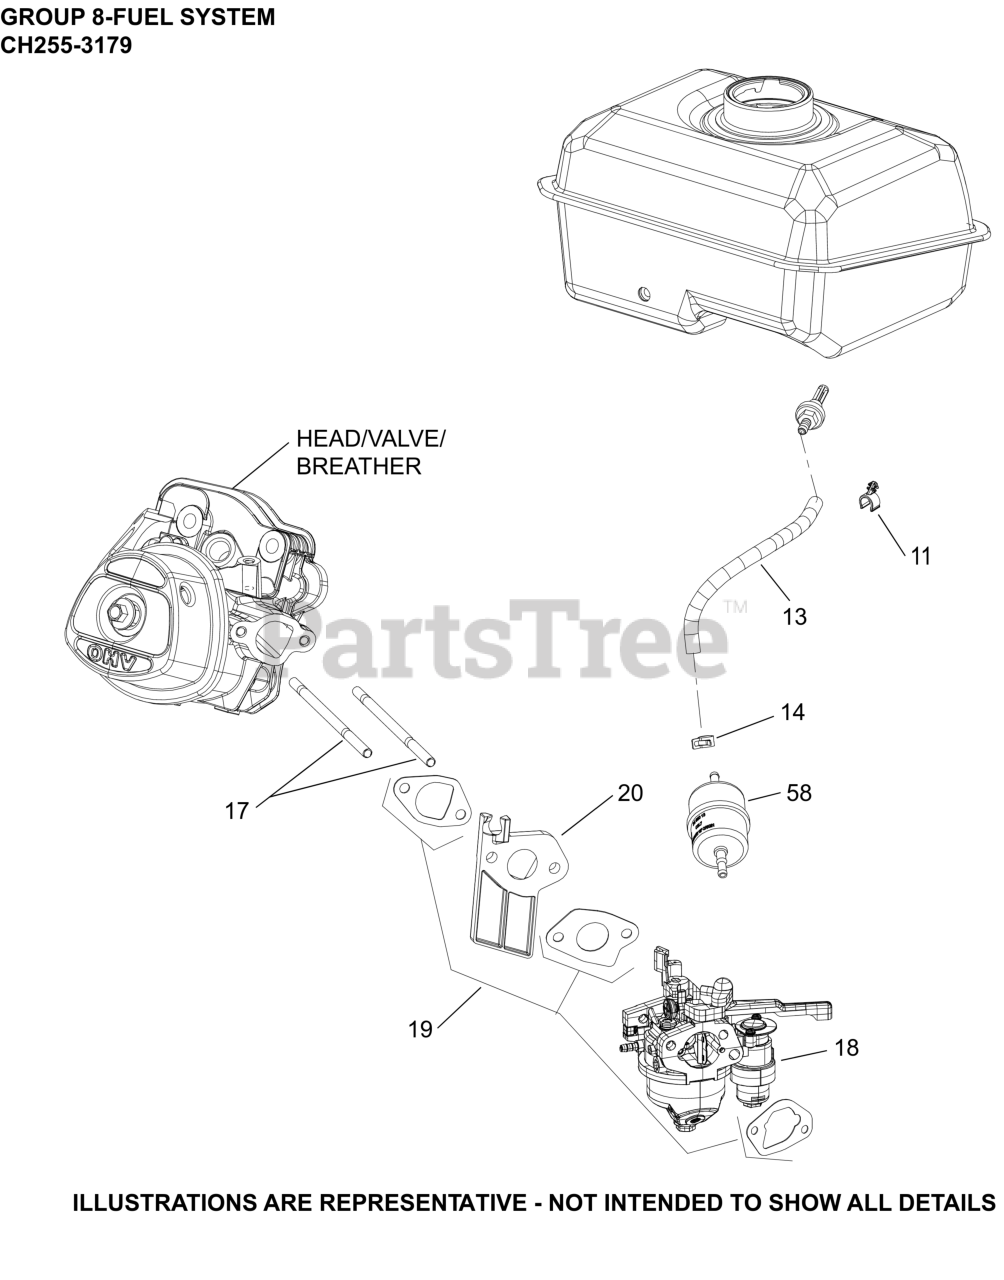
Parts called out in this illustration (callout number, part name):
11	CLIP, FUEL HOSE
13	LINE, FUEL (10"-CUT TO LENGTH)
14	CLAMP, FUEL LINE
17	STUD, CARBURETOR
18	KIT, CARBURETOR
19	KIT, INTAKE GASKET
20	INSULATOR, CARBURETOR
NI	KIT, HIGH ALT (4000-8000 FT)
NI	KIT, HIGH ALT (8,000+ FT)
NI	KIT, CARBURETOR REPAIR (RUIXING)
NI	FILTER, FUEL
